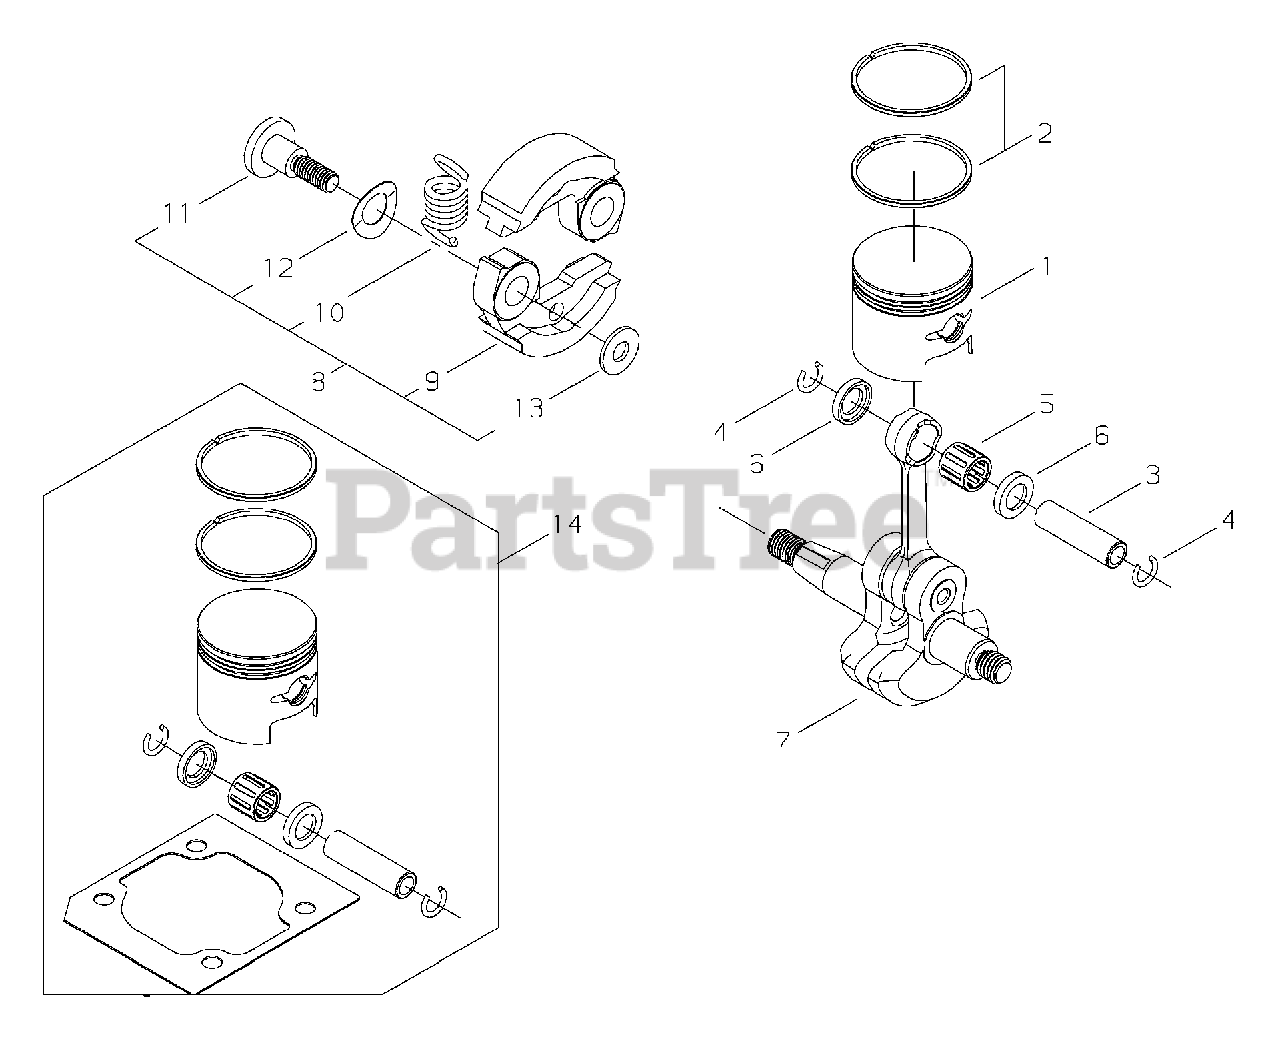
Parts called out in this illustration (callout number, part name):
1	PISTON
2	RING, PISTON
3	PIN, PISTON 8
4	RING, SNAP
5	BEARING, NEEDLE 8
6	WASHER, THRUST 8
7	CRANKSHAFT ASSY
8	CLUTCH ASSY
9	SHOE, CLUTCH
10	SPRING, CLUTCH
11	BOLT, CLUTCH
12	WASHER, SPRING
13	WASHER 6 MM
14	PISTON KIT
